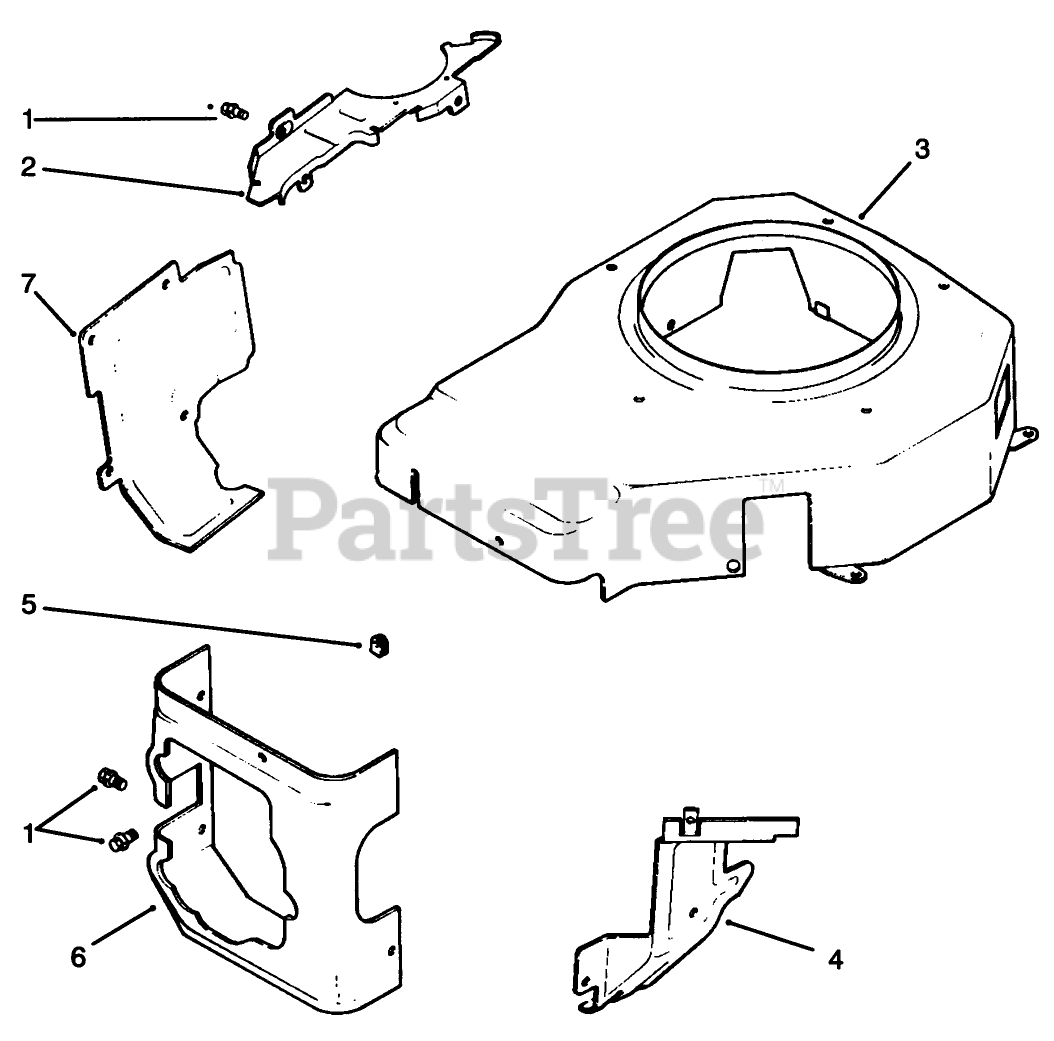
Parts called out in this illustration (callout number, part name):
2	Plate-Blower Housing (Only On: 72042,72043,72062,72063)
3	Housing-Blower (Only On: 72042,72043,72062,72063)
4	Baffle-Carburetor (Only On: 72042, 72043, 72062, 72063)
5	Grommet-Blower Housing (Only On: 72042, 72043, 72062, 72063)
6	Baffle-Cylinder Head (Only On: 72042, 72063, 72062, 72043)
7	Baffle-Cylinder Barrel (Only On: 72042, 72063, 72062, 72043)
